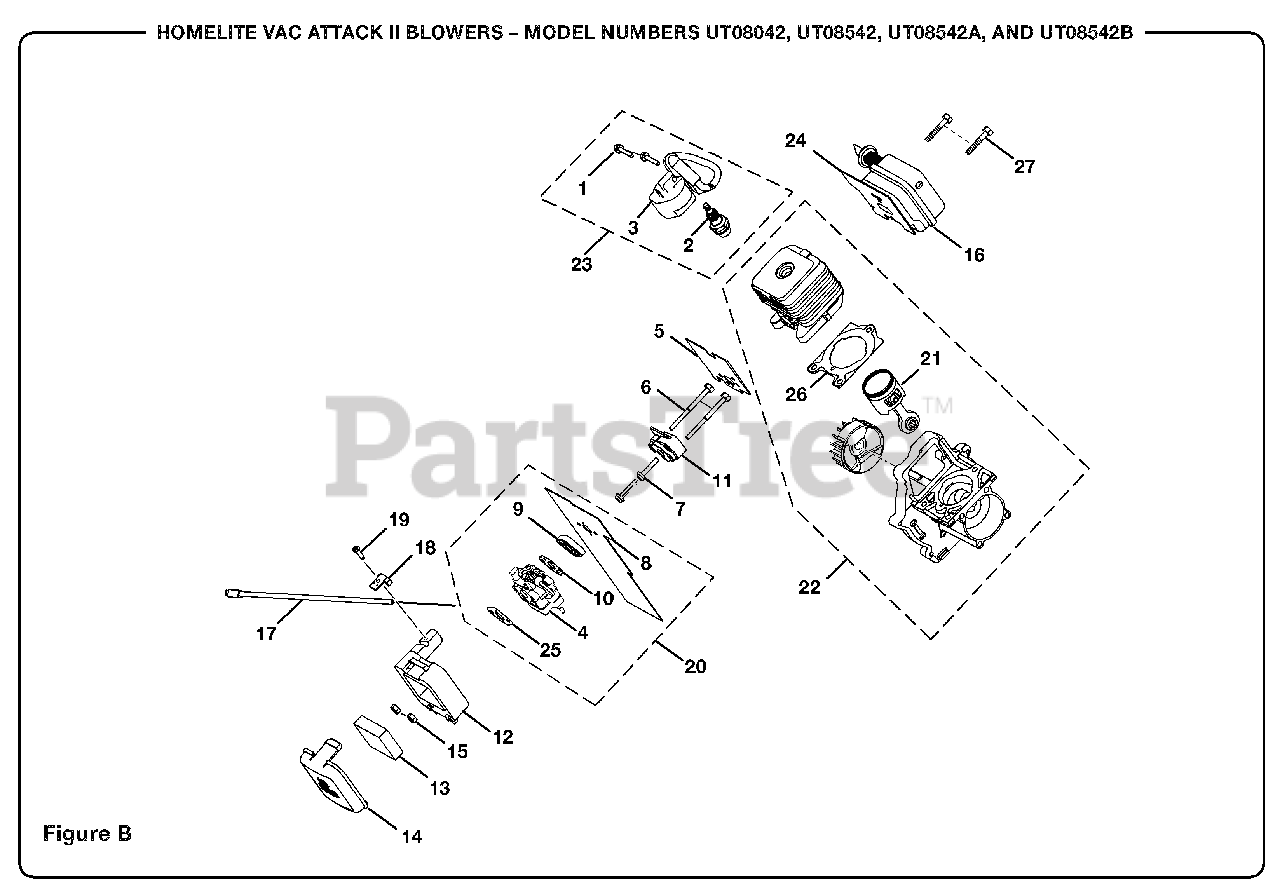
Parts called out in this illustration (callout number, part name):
1	SCREW THD FORMING
2	SPARK PLUG CHAMPION - RCJ-6Y
3	IGNITION MODULE
4	CARBURETOR
5	HEAT DAM GASKET
6	CARBURETOR MOUNTING BOLT
7	SCREW (10-24 x 1.11 PAN HD.)
8	CARBURETOR GASKET
9	SPACER
10	GASKET
11	HEAT DAM
12	AIR FILTER BOX
13	AIR FILTER
14	AIR FILTER COVER
15	HEX NUT (10-24)
16	MUFFLER
17	THROTTLE CABLE
18	THROTTLE CABLE CLIP
19	SCREW-FILTER BOX
20	CARBURETOR KIT
21	PISTON ASSEMBLY KIT
22	SHORT BLOCK ASSEMBLY
23	IGNITION KIT
24	MUFFLER GASKET
26	CYLINDER GASKET
27	SCREW (10-24 x 2-1/2 in. HEX HD.)
